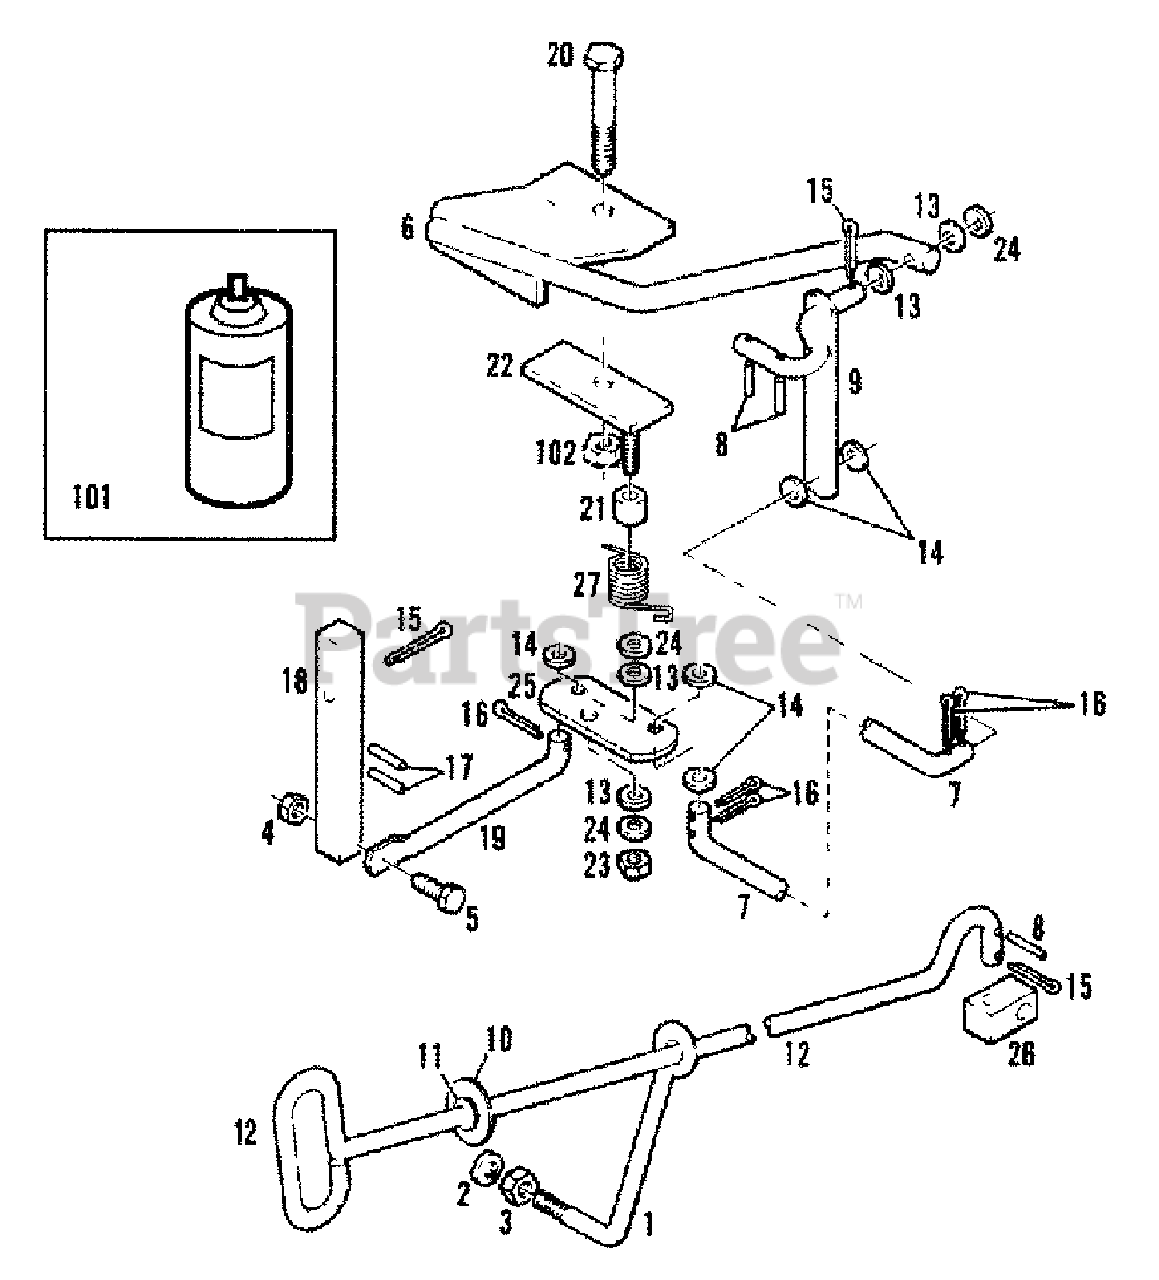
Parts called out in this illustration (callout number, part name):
1	Special Eye Bolt
2	Washer, 3/8
3	Hex Not, 3/8-16
4	Top Locknut, 1/4-20
5	Bolt, 1/4-20 x 1
6	Mounting Plate
7	Link Rod
8	Roll Pin, 1/8 x 3/4
9	Adjustment Lever
10	Instruction Plate
11	Rubber Grommet
12	Rod and Crank Handle
13	Nylon Washer
14	Flat Washer, 5/16
15	Cotter Pin, 1/8 x 3/4
16	Cotter Pin, 3/32 x 1/2
17	Roll Pin, 1/8 x 1
18	Latch Pin
19	Lever Link
20	Bolt, 5/8-1 x 3-1/2
22	Mounting Pad
23	Top Locknut, 3/8-16
24	Flat Washer, 3/8
25	Pivot Latch Lever
26	Swivel Block
27	Torsion Spring
101	Buck Spray Paint 13 oz. can
102	Locknut, 5/8-11
